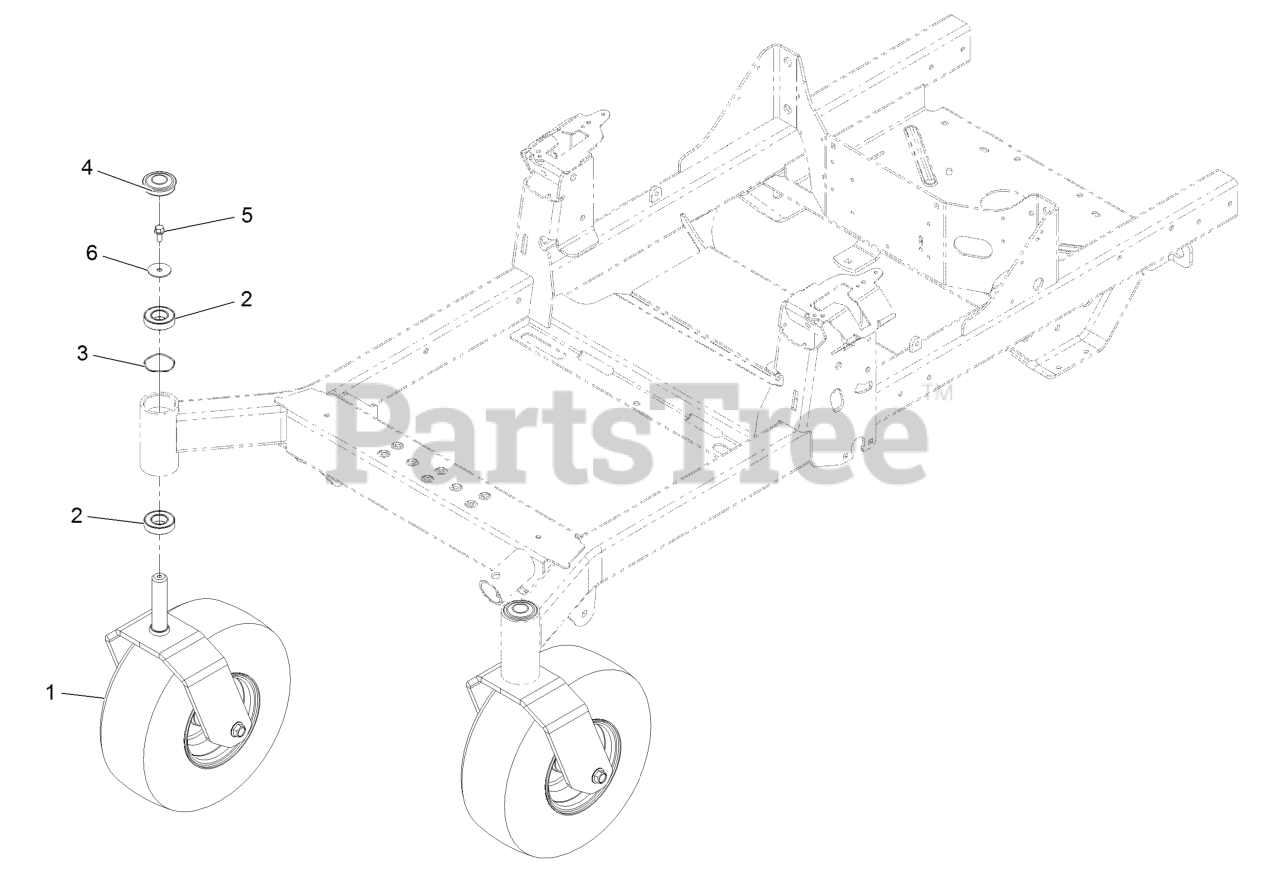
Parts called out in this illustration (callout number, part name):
1	ASM-Front Caster W/Fork
2	Bearing-Ball
4	Cap-Grease
5	Screw-HH Flg 5/16-18 X 3/4
6	Washer-Flat
